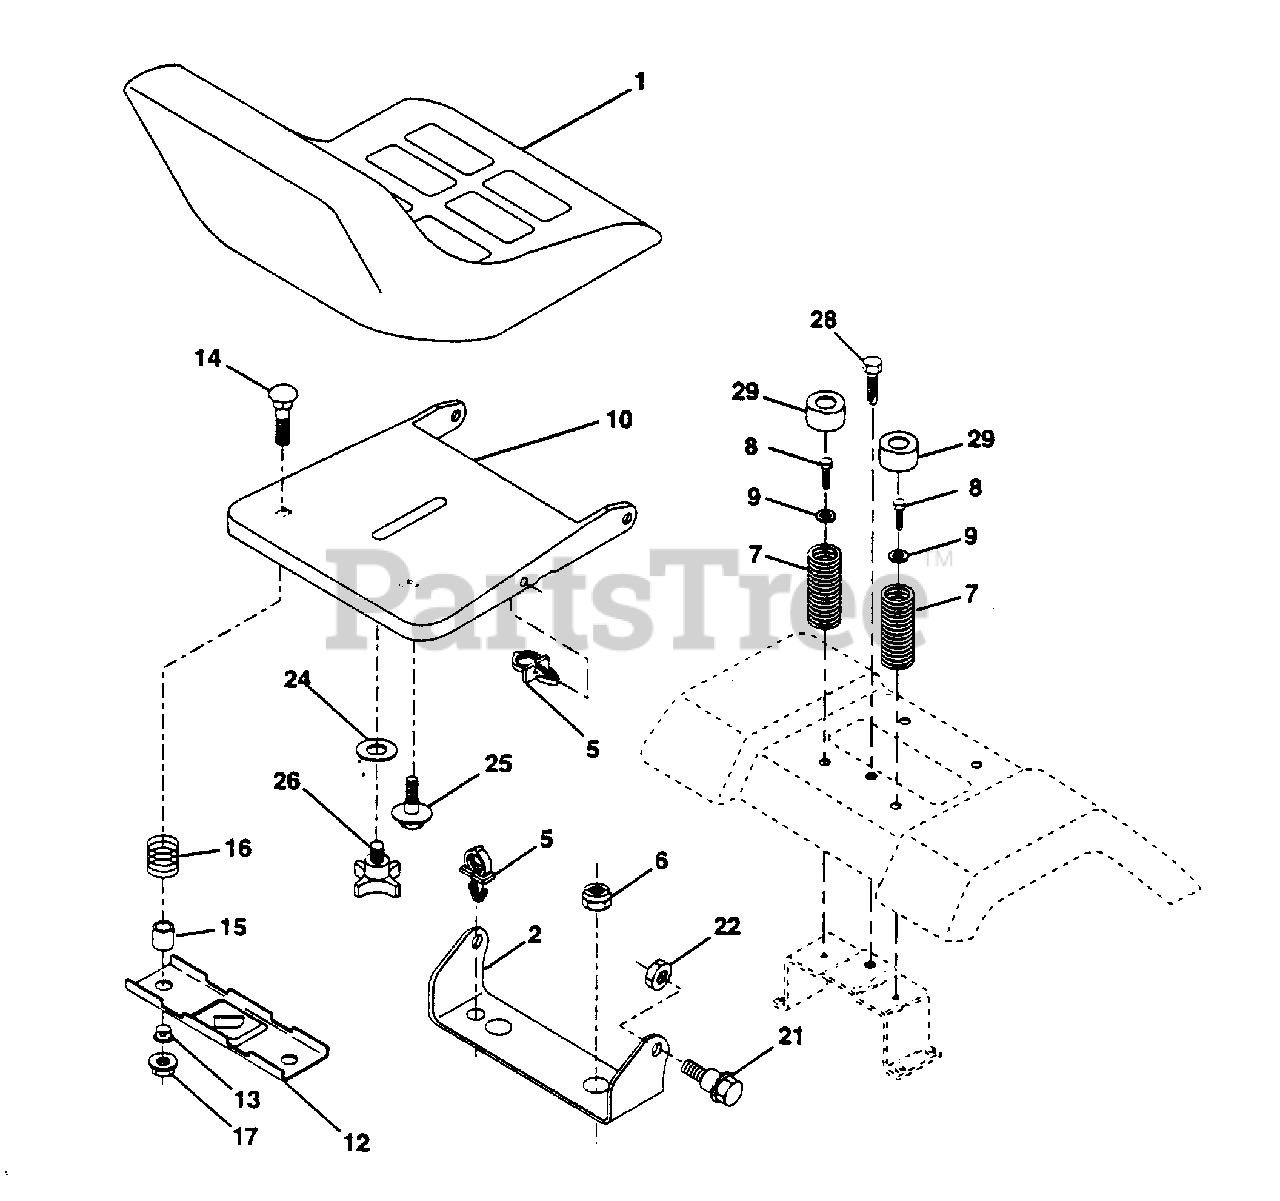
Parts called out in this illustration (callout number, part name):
1	Seat V-560 Blk/blk Std
2	Bracket Pivot Seat 8 720
5	Clip Push-in .375 x .250
6	Nut Crownlock 3/8-16 Unc
7	Spring Seat Cprsn 2 250 Blk Zi
8	Screw Hwsh Thdrol 5/16-18 x 1/2
9	Washer 13/32 X 1 X 14 Ga
10	Pan Seat
12	Bracket Mounting Switch
13	Bushing Snap Blk Nyl 50 Id
14	Bolt Rdhd Sht Nk 1/4-20x1-3/8
15	Spacer Split 28x 88 Yel Zinc
16	Spring Cprsn 1 310 Blk Pnt
17	Nut Lock 1/4 Lge Flg Gr 5 Zinc
21	Bolt Shoulder 5/16-18 Unc Blkz
22	Nut Crown Lock 5/16-18
24	Washer 17/32 X 1-3/16 X 12 Ga
25	Bolt Shoulder 5/16-18 X 62
26	Knob Seat 1/2-13unc Blk
28	Screw Thdrol 3/8 - 16 x 1/2 Ty-TT
29	Cap Spring Seat
